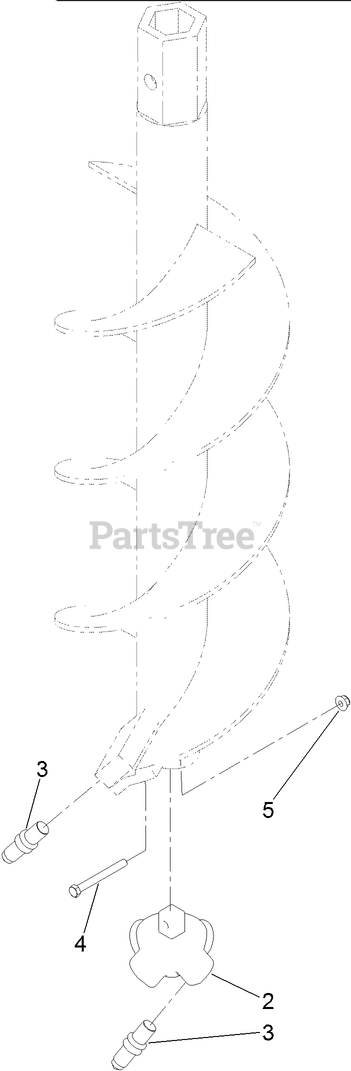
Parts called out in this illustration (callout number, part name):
2	PILOT-AUGER, ROCK
3	TOOTH-BULLET
4	SCREW-HH
5	NUT-HF, NI
